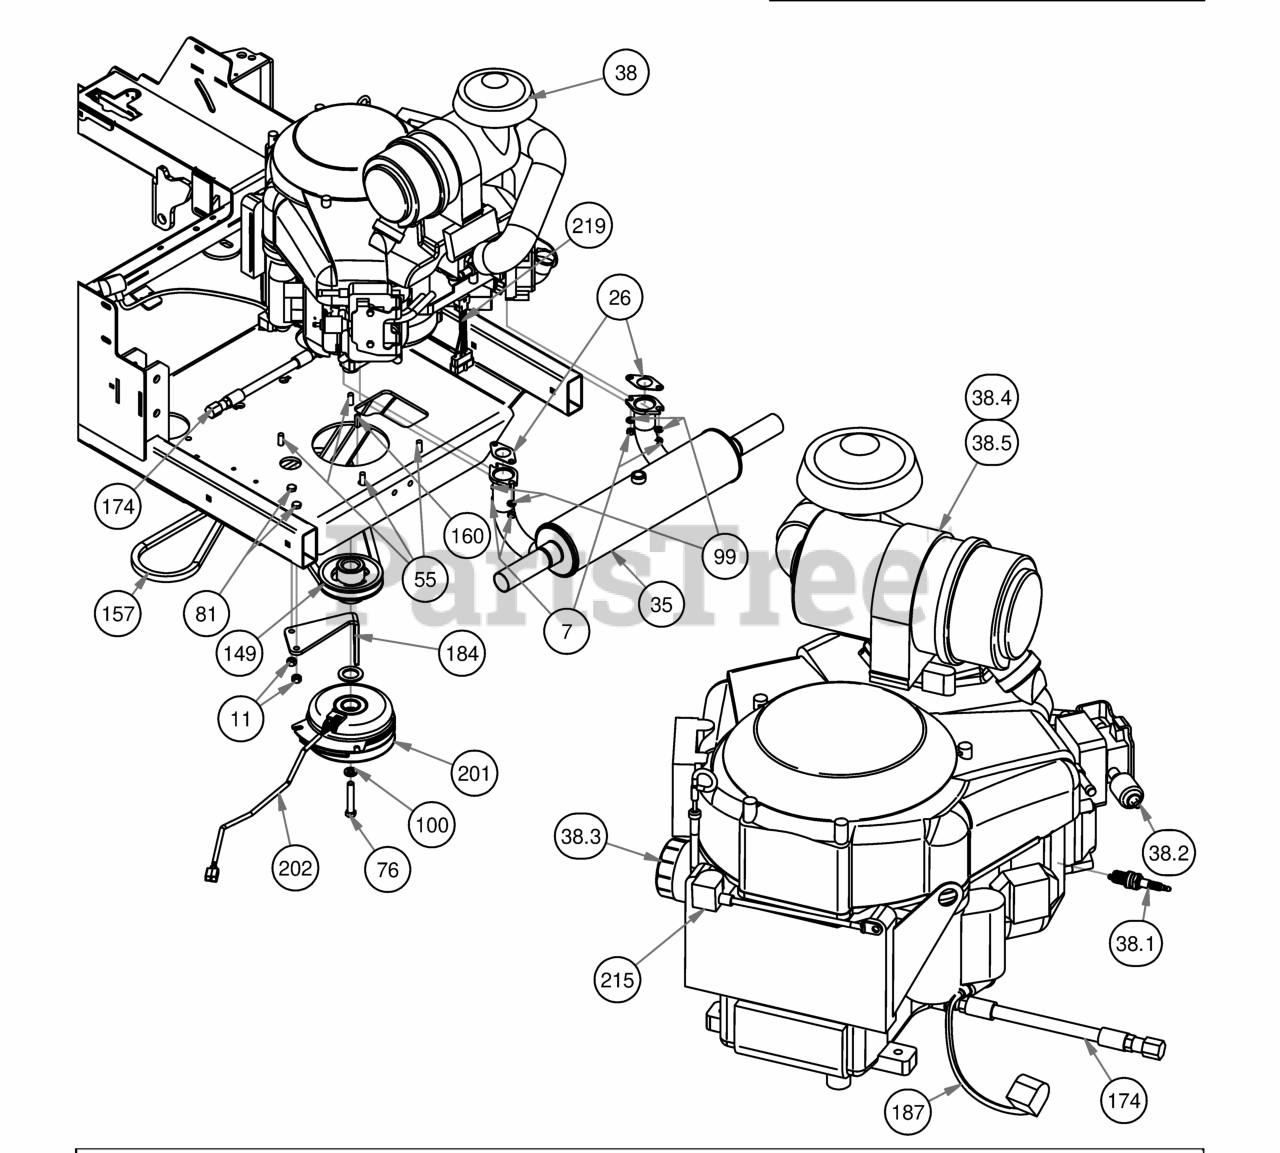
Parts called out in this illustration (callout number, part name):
7	M8-1.25 Zinc Nut
11	3/8" Hex Nut
26	Exhaust Gasket for 23 Vanguard
35	Muffler for 36Hp Vanguard
38	993cc Vanguard Engine
38.1	Spark Plug
38.2	Universal Inline Fuel Filter
38.3	Oil Filter
38.4	Canister Air Filter- Outer
38.5	Canister Air Filter- Inner
55	3/8 x 1 1/8 bolt
76	7/16" x 2 1/2" Hex Bolt
81	3/8" x 1" Hex Bolt
94	1 1/8" Flat Spacer
99	5/16" Lock Washer
100	7/16" Lock Washer
149	4 3/4 Motor Pulley
157	2019 Rogue Pump Belt 68"
160	1/4" x 1" Key
174	14 mm Oil drain Hose 993cc Vanguard
184	PTO Engager Holder
187	24" Red Battery Cable
201	Clutch Assembly
202	Clutch Pigtail
203	2019 Veritical Suspension Frame
215	Starter Cable
219	2019 Harness Adaptor - Vanguard 37 EFI Vert/Horiz
